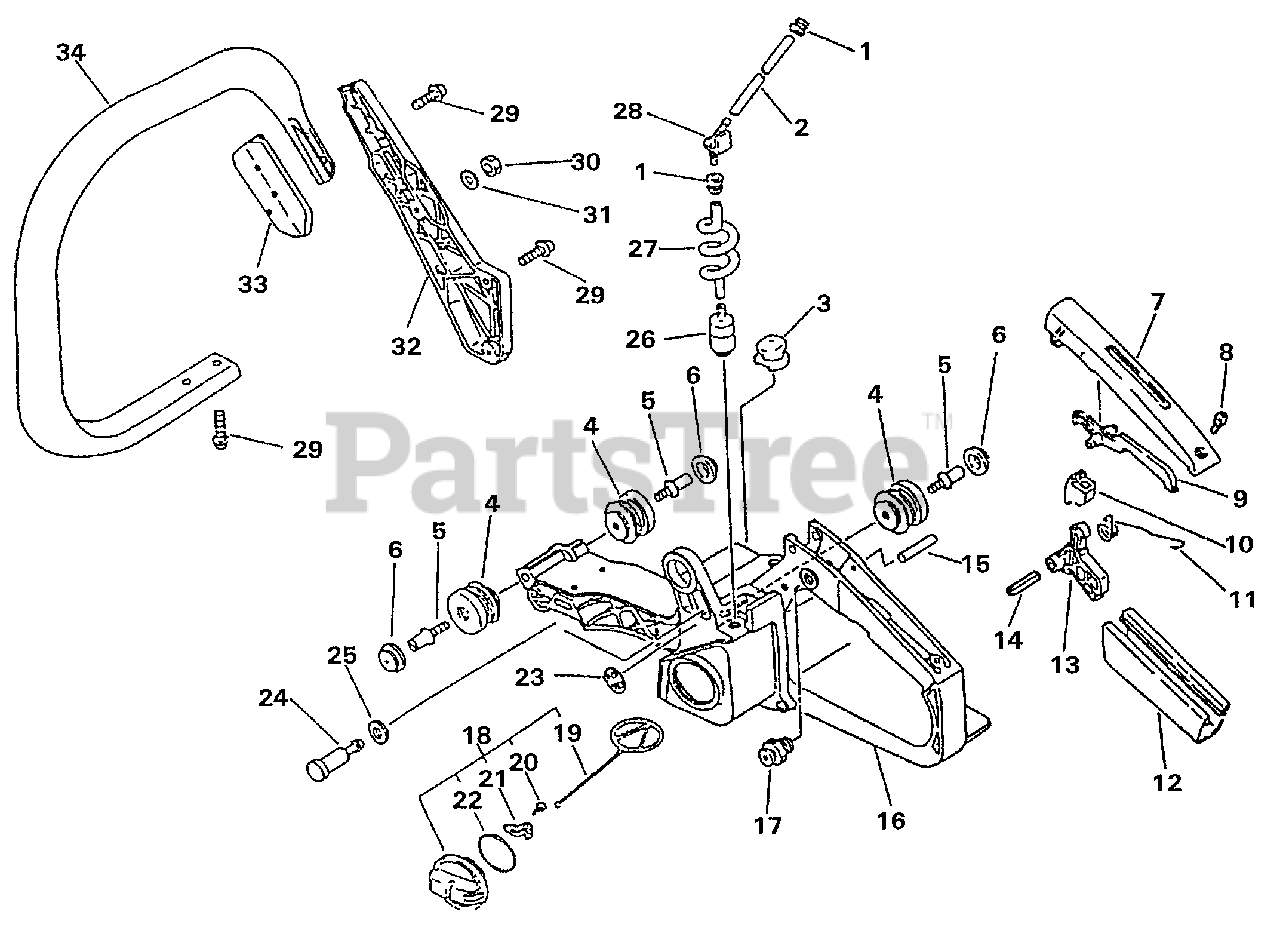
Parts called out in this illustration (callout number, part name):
1	GROMMET
2	PIPE - 3X6X100 -- BLACK
4	CUSHION
6	CAP, CUSHION
7	COVER, HANDLE
8	SCREW - 4X14
9	LEVER, TRIGGER LOCKOUT
11	SPRING, TRIGGER
12	GRIP, HANDLE
13	TRIGGER, THROTTLE
14	PIN - SPRING -- 5X25
15	PIN - 3X26
16	HANDLE - REAR
17	LOCK, THROTTLE
18	CAP ASSY
19	CONNECTOR, CAP
20	SCREW - 3X8
21	RETAINER
22	O-RING - 29
24	VENT, FUEL TANK
25	GROMMET
26	FILTER, FUEL
27	PIPE, FUEL - SPIRAL
28	CONNECTOR, PIPE
29	SCREW - 5X20 -- TAPPING
30	NUT - 5 -- SLOTTED
31	WASHER - 5
32	BRACKET, HANDLE - OUTER
33	BRACKET, HANDLE
34	HANDLE - FRONT
